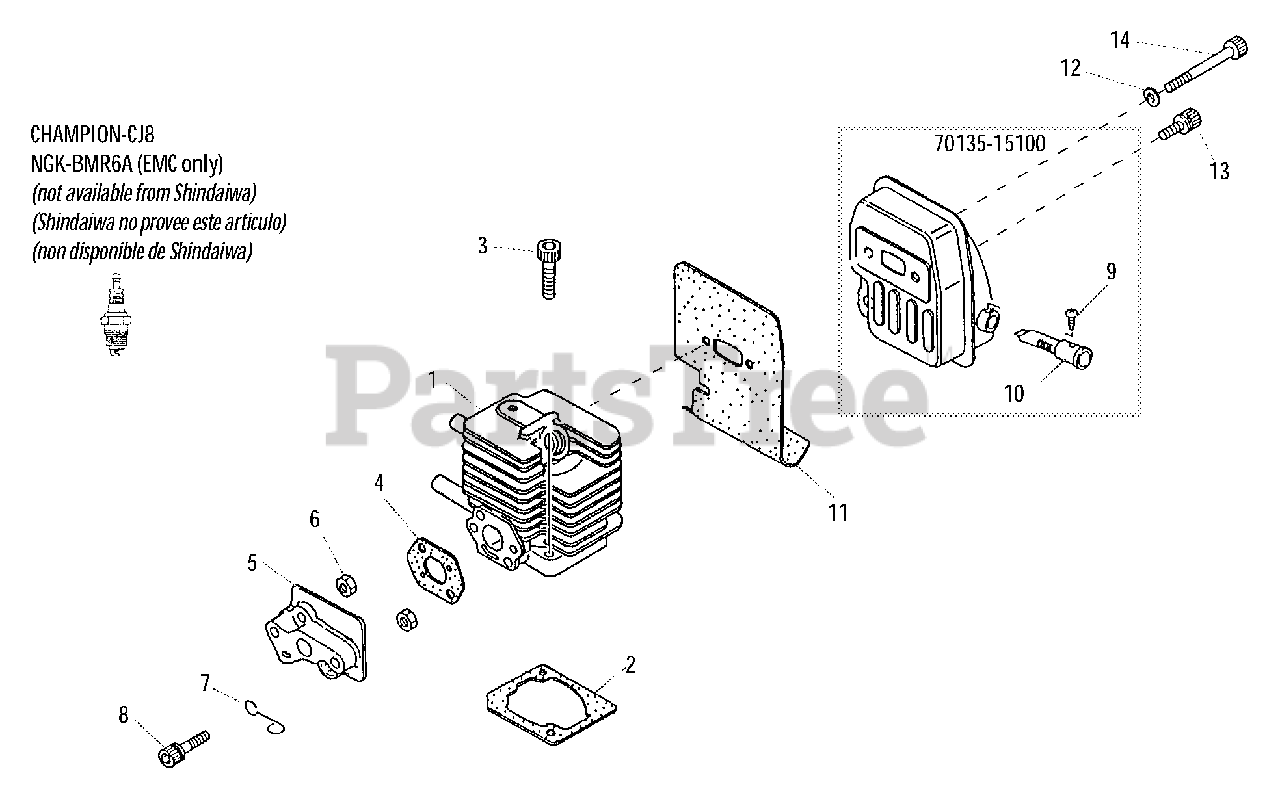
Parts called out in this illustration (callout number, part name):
1	CYLINDER
2	GASKET, CYLINDER
3	BOLT 5×25
4	GASKET
5	INSULATOR BLOCK
6	NUT M5
7	CLIP, VENT ASSY
8	BOLT SS M5×30
9	SCREW, TAPPING 3×6
10	SCREEN, SPARK ARRESTER
11	GASKET, EXHAUST
12	WASHER, FLAT 5.5×10×0.8
13	BOLT 5×12
14	BOLT M5×50
70135-15100	MUFFLER ASSY
